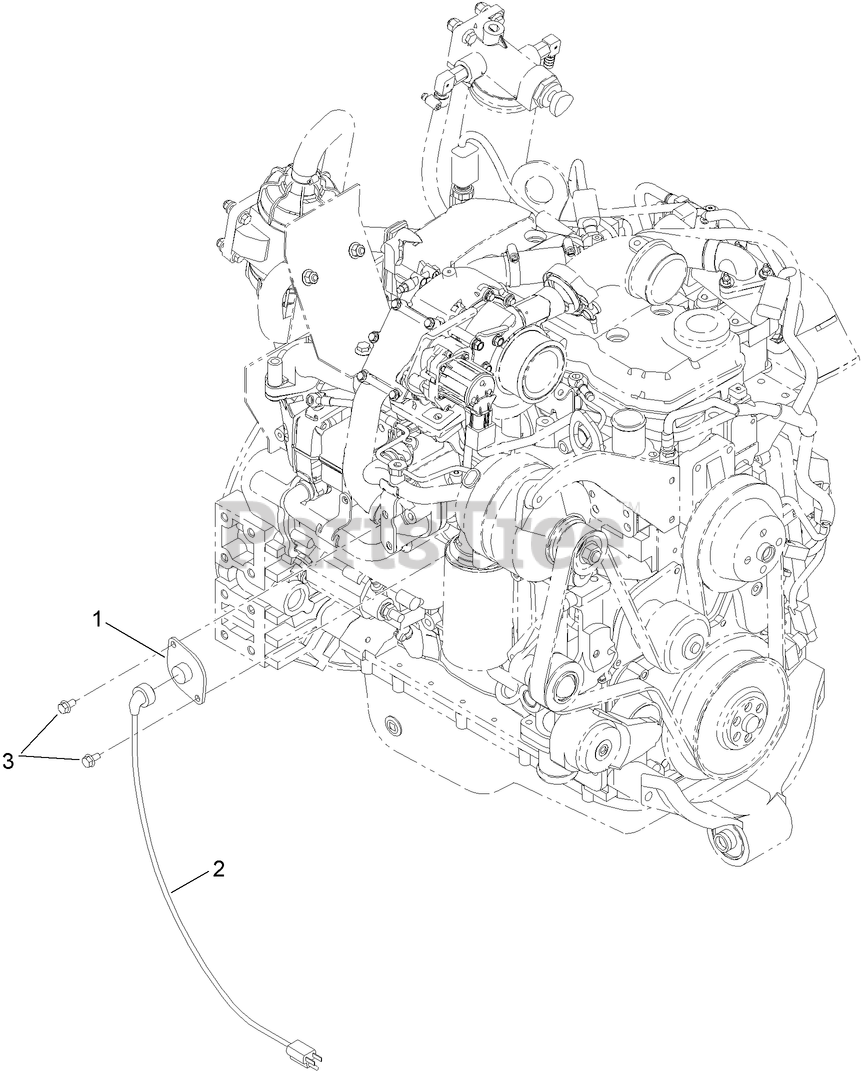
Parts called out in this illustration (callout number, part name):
1	HEATER-COOLANT/BLOCK, 12V
2	6 FOOT CORD ASM
3	SCREW-HHF
